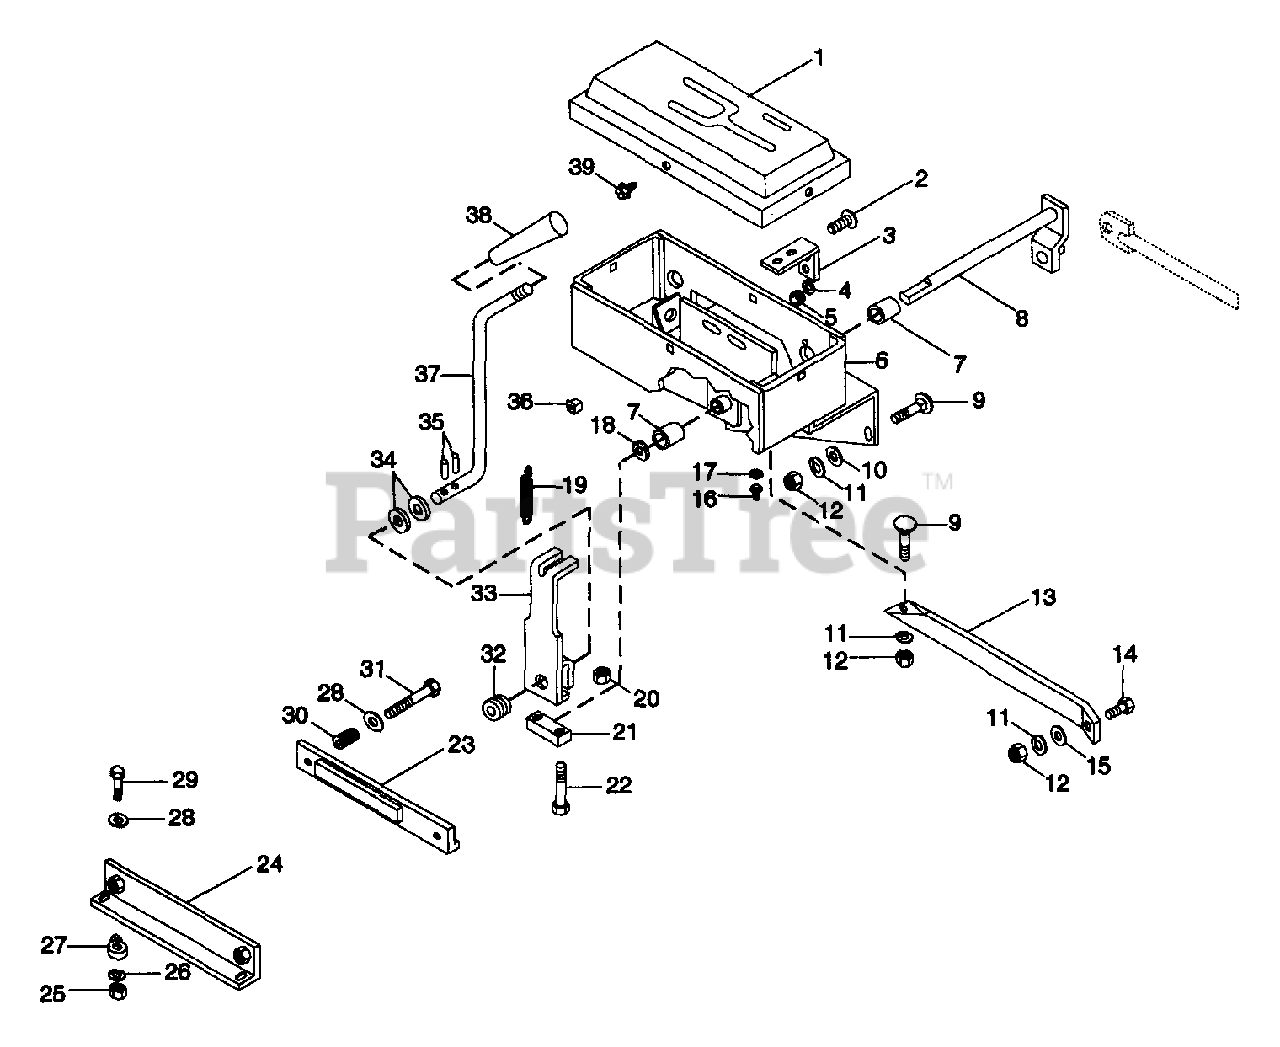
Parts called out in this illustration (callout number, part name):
1	CONTROL CONSOLE
2	SCR-MCH 10-24X.50 SLRH PL
3	SWITCH BRACKET
4	WSHR-LK 10X.047 MED PL
5	NUT-HEX 10-24 PL
6	CONTROL BOX
7	BSHG-SLV .625X.750X1.000
8	SHIFT SHAFT
9	BLT-RDHDSQSHNK .38-16X1.00 PL
10	WSHR-FL-STL .438X1.0X.083 PL
11	WSHR-LK .375X.094 MED PL
12	NUT-HEX .375-16
14	BLT-HEX .38-16X.75 PL GR2
15	WSHR-FL-STL.406X.812X.065PL
16	SPIN DRIVE ZERK FITTING
17	WSHR-LK .250X.047 LT PL
18	WSHR-FL-STL .630X1.005X.062 PL
19	SG-TENS .072X.565X1.87
20	NUT-LK-TOP .312-18 GR C PL
22	BLT-HEX .31-18X1.50 PL GR5
23	L. H. FRICTION BRAKE
24	R.H. FRICTION BRAKE
25	NUT-HEX .312-18
26	WSHR-LK .312X.097 PL HVY
27	SPACER .344X.750X.625X.500
28	WSHR-FL-STL .323X.625X.062 PL
29	BLT-HEX .31-18X1.25 PL GR2
30	SG-COMP .093X.59X1.50
31	SCR-MCH .31-18X2.75 SLRH PL
32	GROMMET .438ID X .688 OD
34	WSHR-FL-STL .520X.827X.062 YZ
35	PIN-ROLL .188X.88
36	PLASTIC GROMMET
37	SHIFT ROD
39	SCR-TAP 10-12X.50 CRPH PL A
